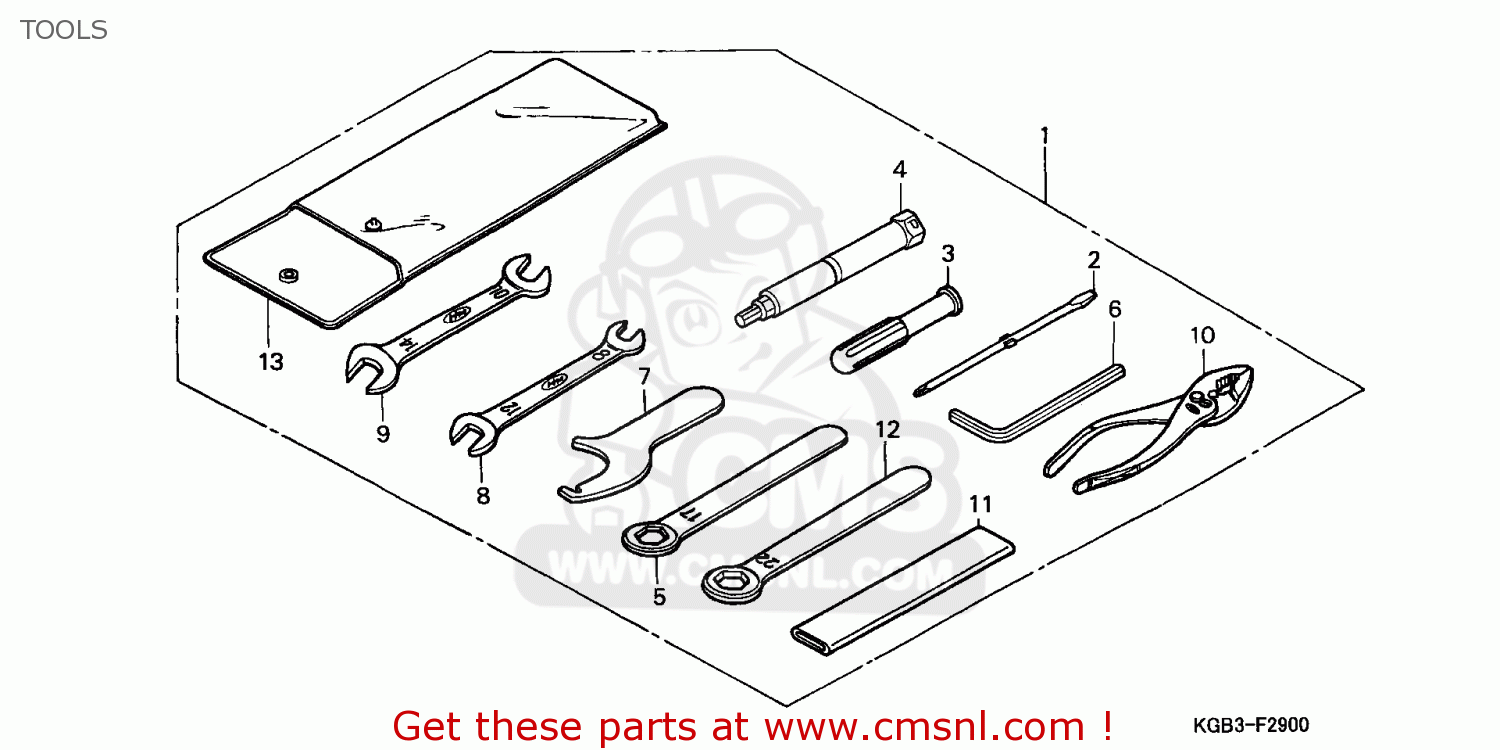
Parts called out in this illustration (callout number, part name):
1	TOOL SET
2	SCREWDRIVER
3	GRIP,DRIVER
4	WRENCH,PLUG 16
5	FYE WRENCH,17
6	WRENCH,HEX.,5MM
7	SPANNER,PIN
8	SPANNER TLS812
9	SPANNER, 10X14
10	PLIER 135
11	HANDLE,EYE WRENCH
12	EYE WRENCH,22
13	BAG,TOOL
